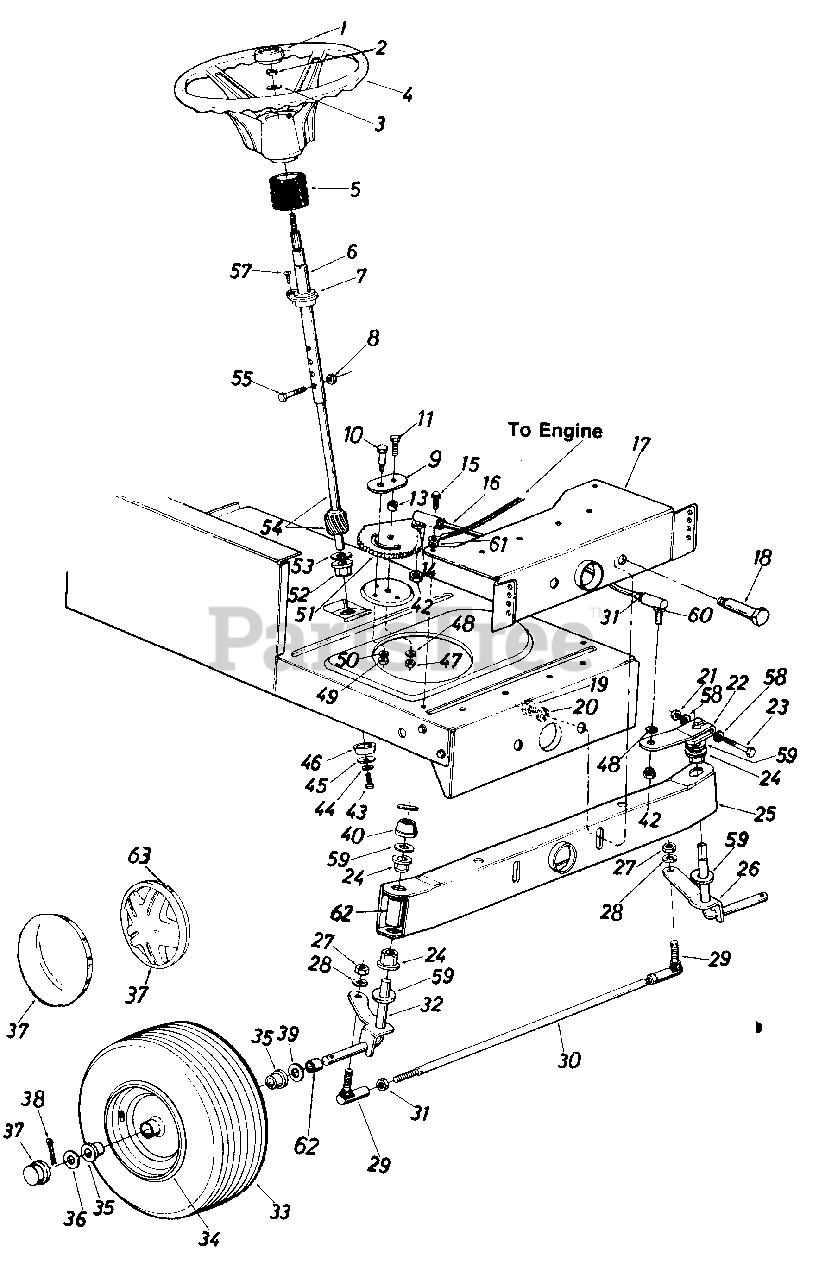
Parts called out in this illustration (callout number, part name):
1	Steering Wheel Cap
2	Hex L-Nut 5/16-24 Thd.
3	Belleville Wash. .345" I.D.
4	Steering Wheel (3 Spoke)
5	Steering Bellow-4.5"
6	Steering Column Ass'y.
7	Flange Bearing .890 I.D. x 1.36 O.D.
8	Hex L-Nut 1/4-20 Thd.
9	Retainer Plate
10	Shoulder Bolt .437" Dia. x .35 Lg. 5/16-18 Thd.
11	Hex Bolt 3/8-24 x 1.0" Lg. (Grade 5)
13	Spacer .380" I.D. x .625" O.D. x .227
14	L-Wash. 3/8" I.D.
15	Hex Wash. Hd. Self-Tap Scr.
16	Steering Drag Link
17	Front Pivot Brkt.
18	Shoulder Bolt .498" Dia. x 2.04 Lg. 3/8-16 Thd.
19	Hex Nut 3/8-16 Thd.
20	L-Wash. 3/8" I.D.
21	Hex Cent. L-Nut 5/16-24 Thd.
22	Steering Arm Front Axle
23	Hex Bolt 5/16-24 x 2.00" Lg. (Grade 5)
24	Hex Flg. Brg. .634 I.D.
26	Front Axle Ass'y.-L.H.
27	Hex Nut 3/8-24 Thd.
28	L-Wash. 3/8" I.D.
29	Ball Joint 3/8-24 Thd.
30	Tie Rod
31	Hex Jam Nut 3/8-24 Thd.
32	Front Axle Ass'y.-R.H.
33	Wheel Ass'y. Comp.
34	Front Wheel Rim Only
35	Bearing
36	Fl-Wash. .635 I.D. x 1.59 O.D.
37	Front Wheel Hub Cap
38	Cotter Pin 1/8" Dia. x 1.25"
39	Fl-Wash. .640" I.D. x 1.24" O.D.
40	Push Cap 5/8" Dia. Rod
42	Hex Jam Nut 3/8-24 Thd.*
43	Hex L-Bolt 5/16-18 x .62"
44	L-Wash. 5/16" I.D.
45	Fl-Wash. .33" I.D. x 1.25" O.D.
46	Spacer (Plastic)
47	Hex Nut 3/8-24 Thd.
48	L-Wash. 3/8" I.D.
49	Hex Nut 5/16-18 Thd.*
50	L-Wash. 5/16" I.D.
51	Steering Gear Segment
52	Hex Flg. Brg. .634 I.D.
53	Fl-Wash. (Hardened)
54	Steering Shaft Lower
55	Hex Bolt 1/4-20 x 1.25" Lg.
57	Oval Hd. Cr.-Sunk Scr. #10 x 5/8" Lg.
58	Wave-Wash. .32" I.D. x .62" O.D.
59	Fl-Wash. (Hardened)
60	Drag Link Ball Joint 3/8-24 Thd.
61	Ext. L-Wash. 5/16" I.D.
62	Plastic Tube
63	Spring Clip
